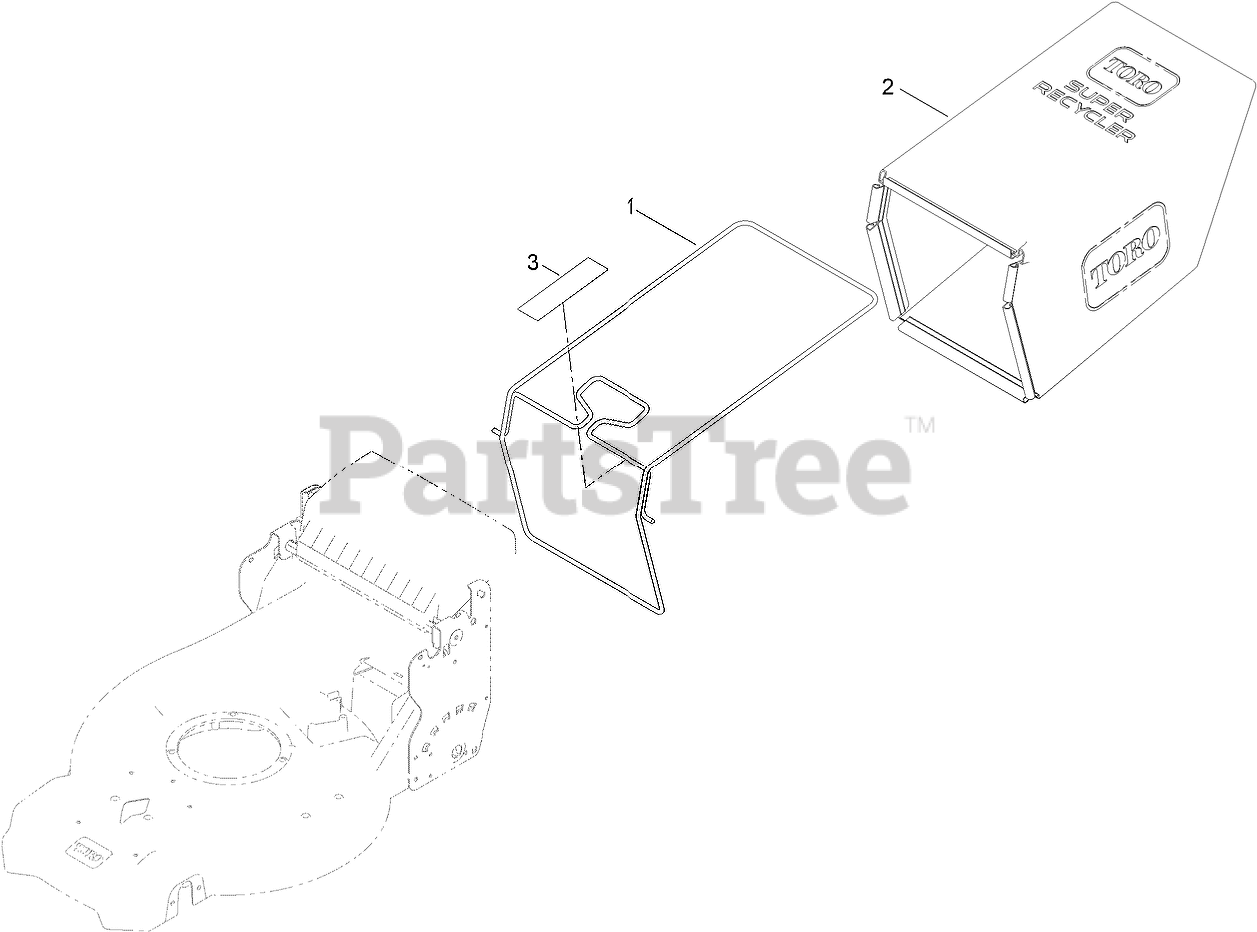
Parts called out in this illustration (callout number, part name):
1	ASM-FRAME, BAG
2	ASM-BAG, GRASS
3	Decal-Warning
